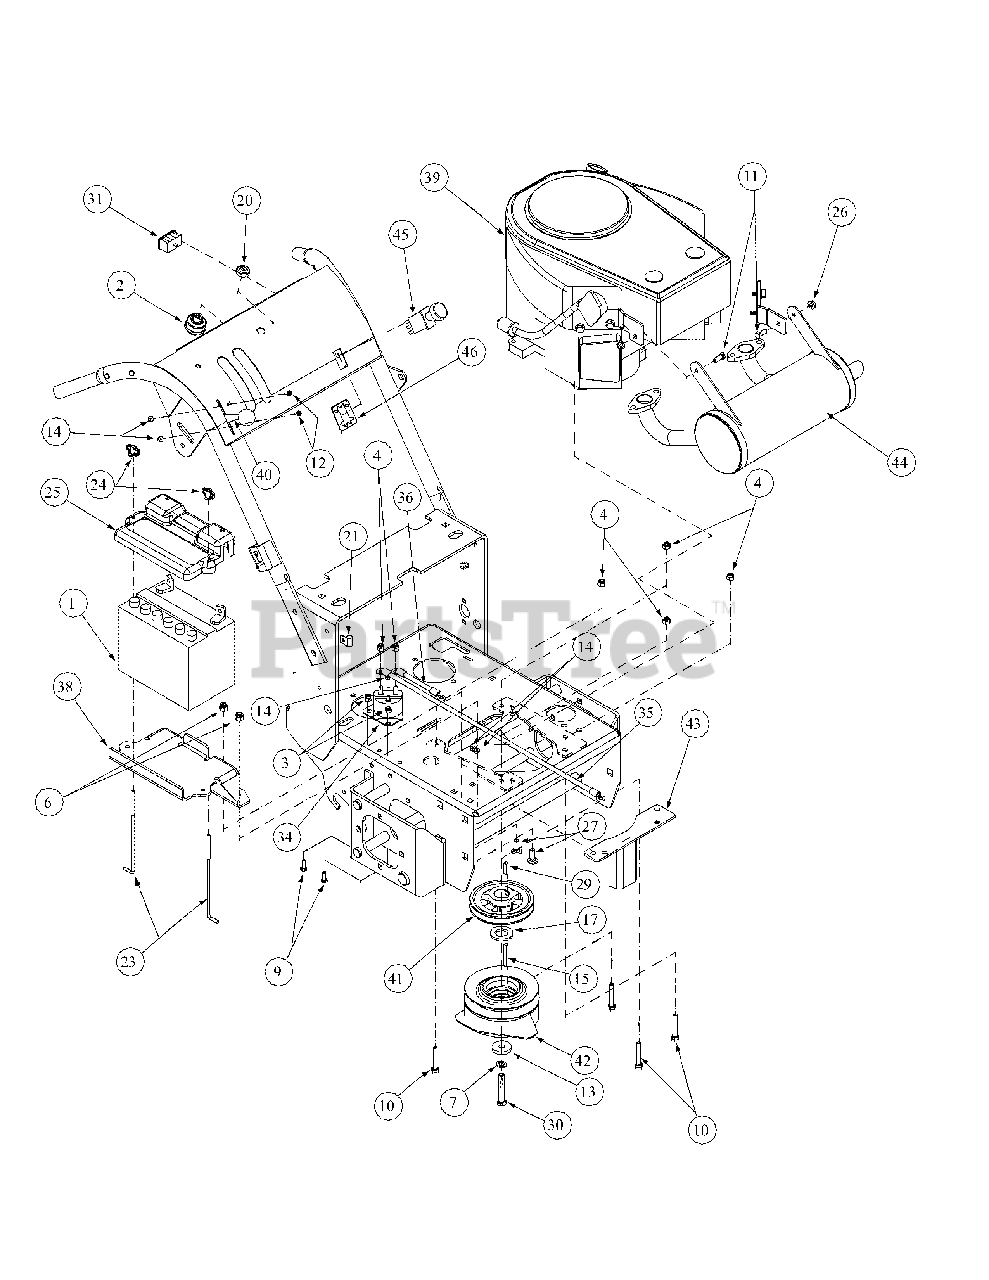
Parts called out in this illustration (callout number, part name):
1	Battery, 12V
2	Ignition Switch
3	Lock Nut Nylon Insert, 1/4-20
4	Nut, 5/16-18, Nylock
6	Lock Nut, Nylon Insert, 3/8-16
7	Lock Washer, 7/16
9	Hex Cap Screw, 1/4-20, .75
10	Hex Cap Screw, 5/16 -18 x 2
11	Hex Cap Screw, 5/16-18 x 3/4
12	Screw, Hex Washer w/Slot, 10-32 x 1/2
13	Plated Clutch Washer
14	Lock Nut, Nylon Insert, 10-32
15	Key Stick, 1/4 x 1/4 x 2
16	Lock Nut, 5/16-18
17	Special Washer
20	Nut, w/Cap, 5/8-32 Ignition
21	Support Clamp, 3/8 OD
23	Battery Hold Down Rod
24	Wing Nut, 1/4-20 w/Bell Wash
25	Large Battery Cover
26	Hex Flange Lock Nut, 5/16-18
27	Carriage Bolt, 3/8-16 x 1
29	Keystick; 1/4 x 1/4 x 1
30	Capscrew, 7/16-20 x 1.75
31	Hour Meter
34	Magnetic Solenoid Switch
35	Red Battery Cable 24"
36	Red Battery Cable 5"
38	Battery Bracket
39	19 Hp Twin Kawasaki Engine
40	Throttle Control, w/detent, 47.25
41	Sheave, 1.125 Bore, w/2 Set Screws
42	Electric Clutch
43	Clutch Ret Assembly Ogura 1.125 ID
44	Muffler Kawasaki, w/brackets
45	Blade Clutch Switch
45	Control Throttle w/Detent
46	Retainer Clip
46	Muffler Bracket
47	Hour Meter
48	17 HP Kawasaki Engine
49	Blade Clutch Switch
